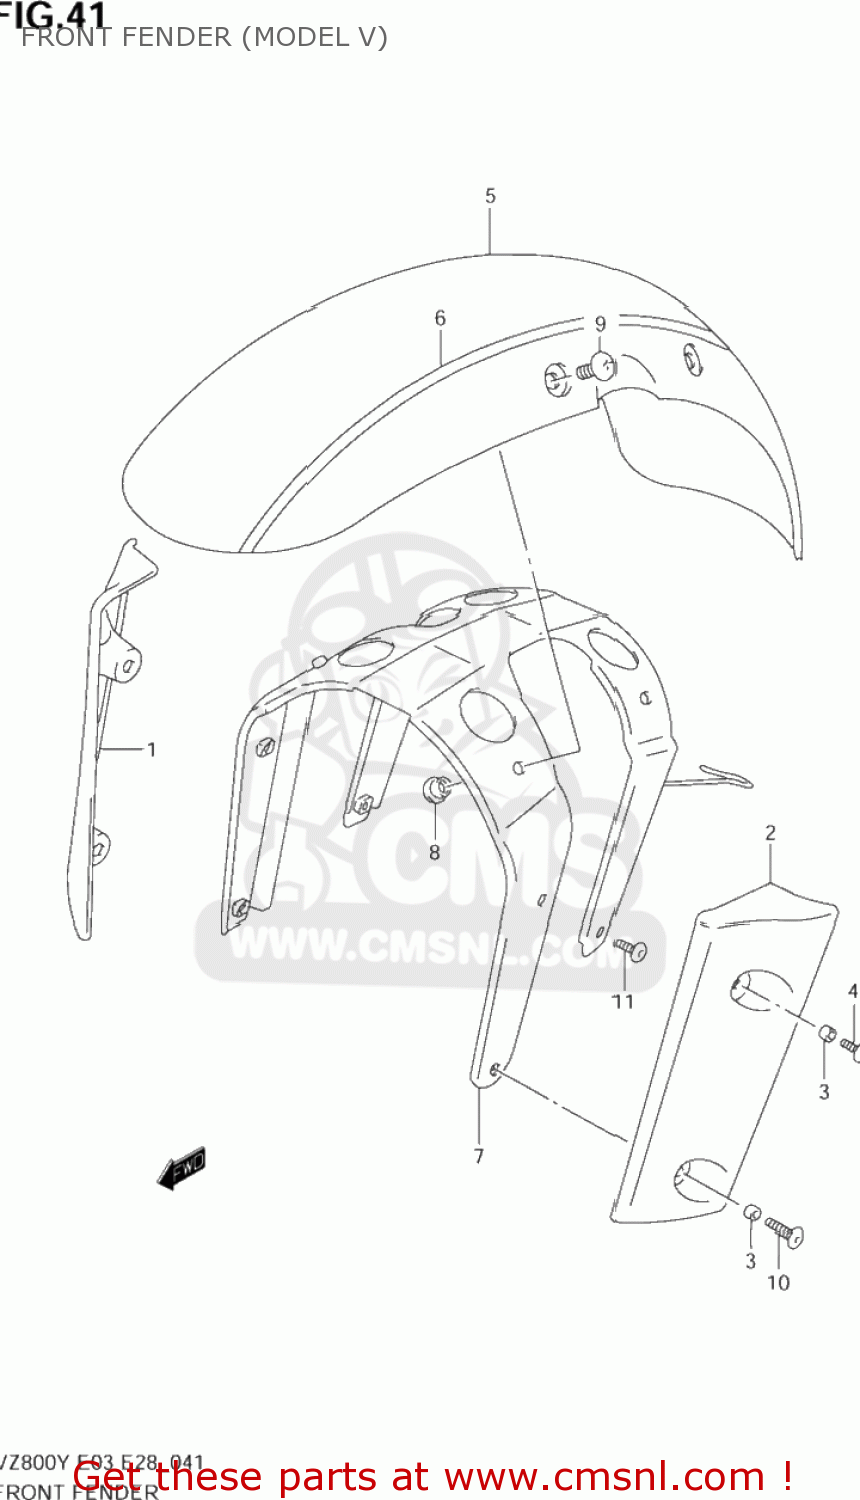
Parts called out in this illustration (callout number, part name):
1	COVER,FR FORK SIDE,R
2	COVER,FR FORK SIDE,L
3	SPACER(6.1X8X3.5)
4	SCREW(6X12)
5	FENDER SET,FR
6	TAPE SET,FR FENDER
7	BRACE,FR FENDER
8	NUT
9	SCREW(6X12)
10	SCREW(6X20)
11	SCREW(6X16)
